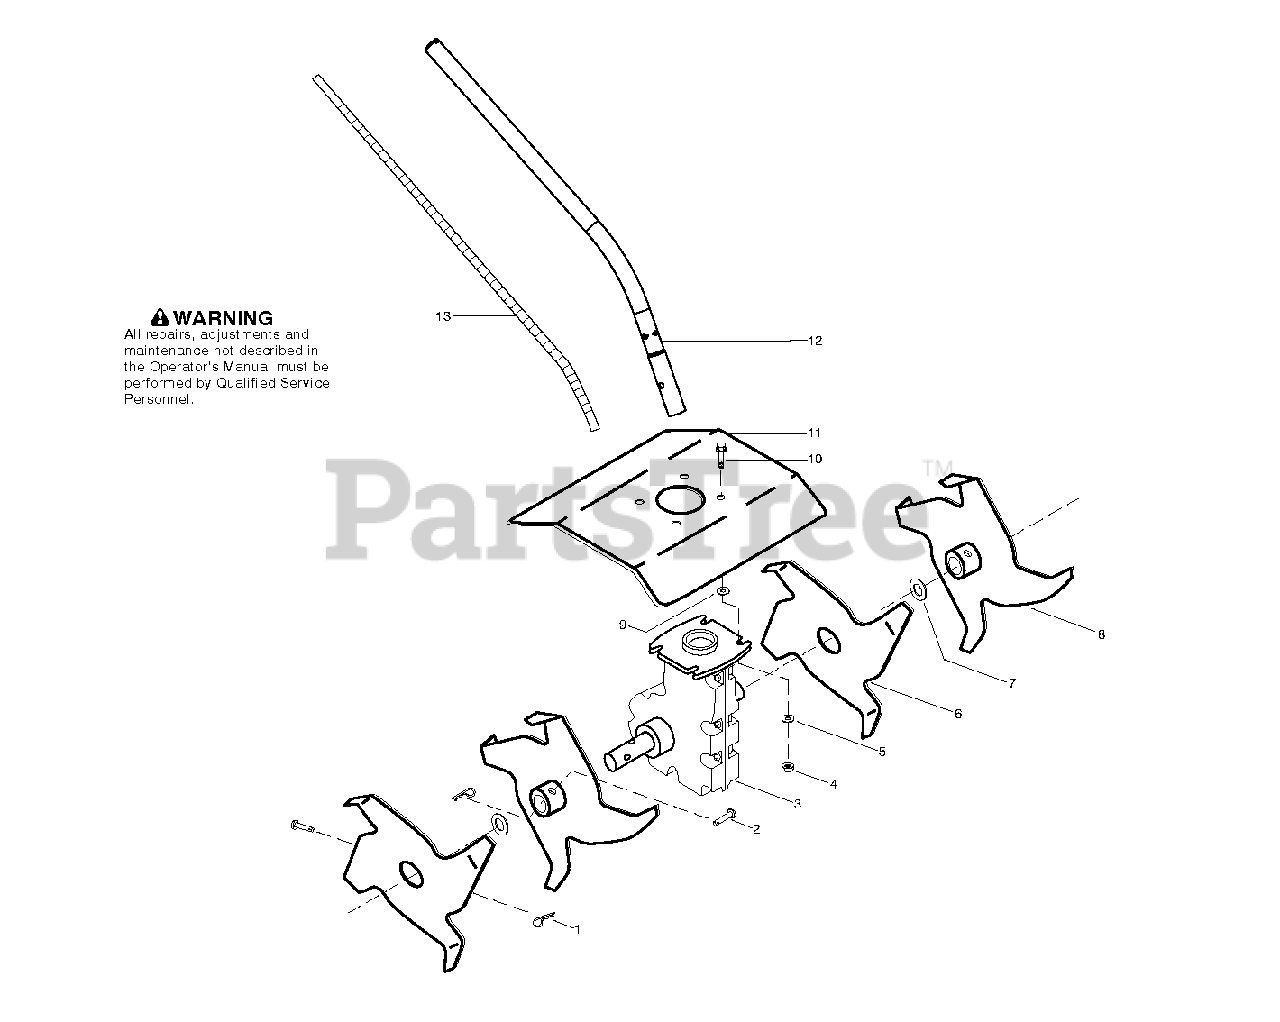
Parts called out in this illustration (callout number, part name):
1	RETAINER,HAIRPIN
2	PIN,CLEVIS
3	GEARBOX
5	WASHER,FLAT
6	TINE,RIGHT OUTSIDE/LEFT INSIDE
7	WASHER,FELT
8	TINE,LEFT OUTSIDE/RIGHT INSIDE
9	WASHER,FLAT
10	BOLT,WASHER HEAD
11	KIT,GUARD
